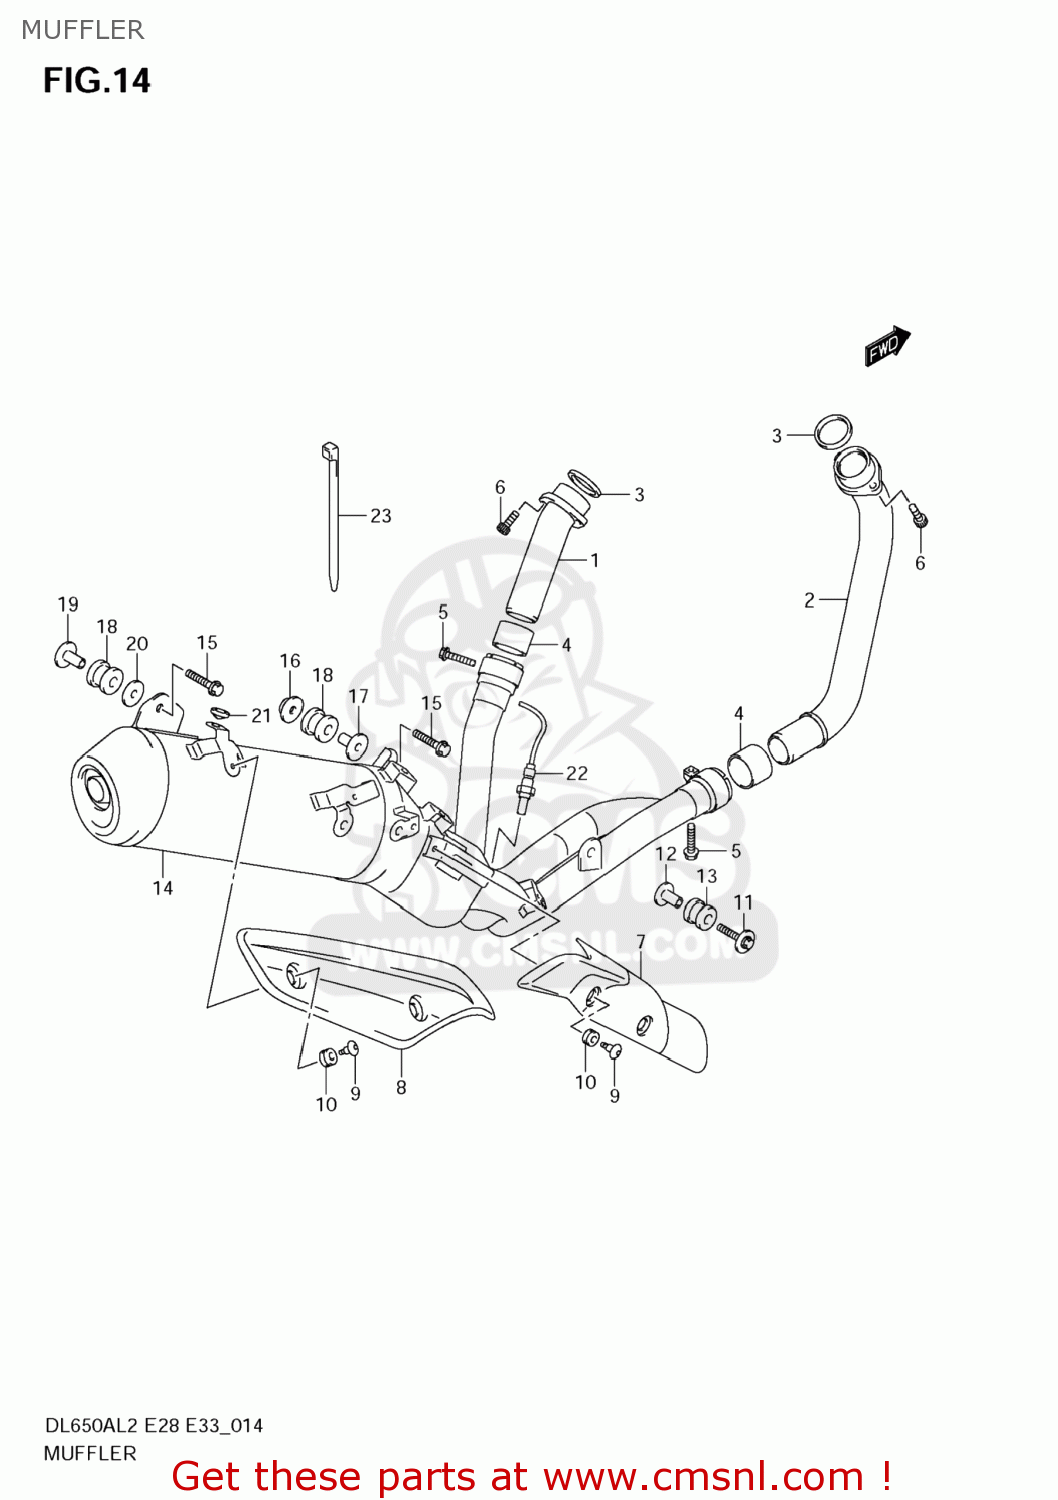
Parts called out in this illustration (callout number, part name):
1	PIPE,EXHAUST RR
2	PIPE,EXHAUST FR
3	GASKET,EXHAUST PIPE (NAS)
4	CONNECTOR,EXHAUST
5	BOLT(8X35)
6	BOLT(8X25)
7	COVER,MUFFLER FR
8	COVER,MUFFLER
9	SCREW(6X20)
10	CUSHION
11	BOLT(8X45)
12	SPACER(8.6X12X24.2)
13	CUSHION
14	MUFFLER
15	BOLT(8X45)
16	NUT,MUFFLER SUPPORT FR
17	SPACER(8.6X12X27.1)
18	CUSHION
19	NUT,MUFFLER SUPPORT
20	WASHER(8.5X33X1.5)
21	CUSHION
22	SENSOR,OXYGEN
23	CLAMP(L:145)
